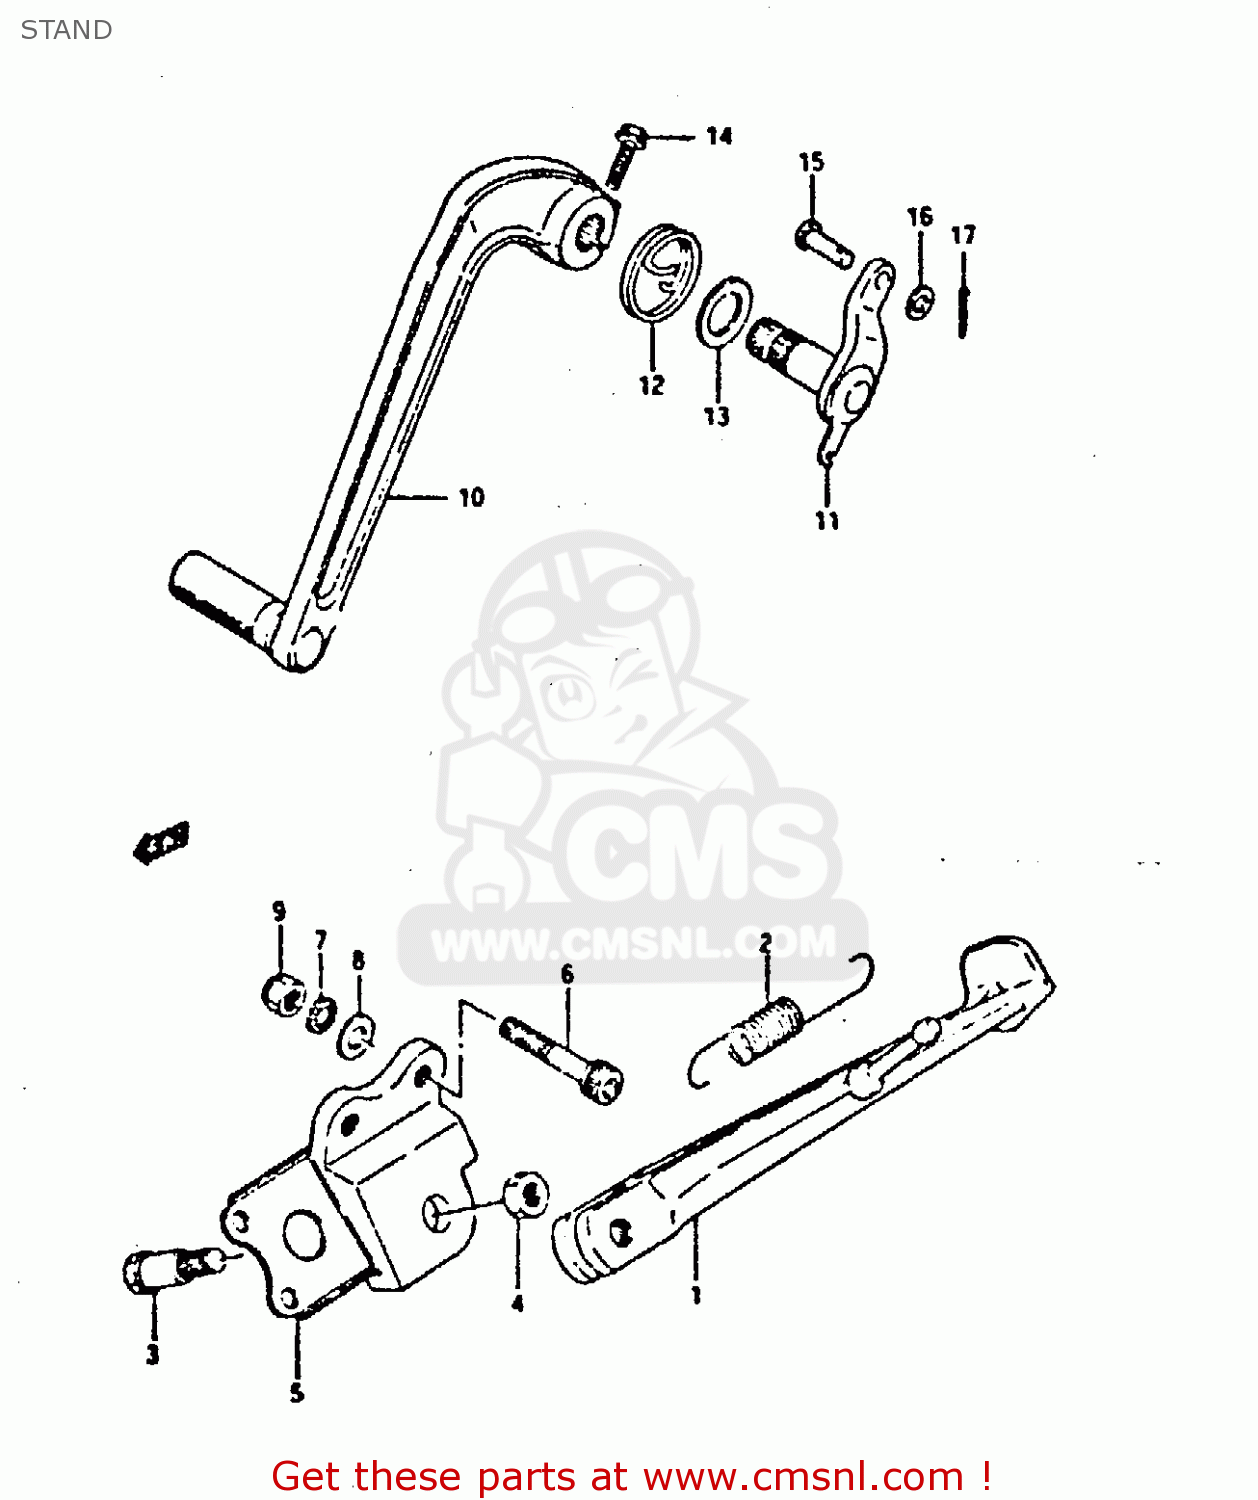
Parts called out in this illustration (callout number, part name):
2	SPRING
3	BOLT L:30
4	NUT
6	BOLT
7	WASHER
8	WASHER
9	NUT
13	WASHER,BRAKE PEDAL
14	BOLT
15	PIN
16	WASHER
17	PIN
